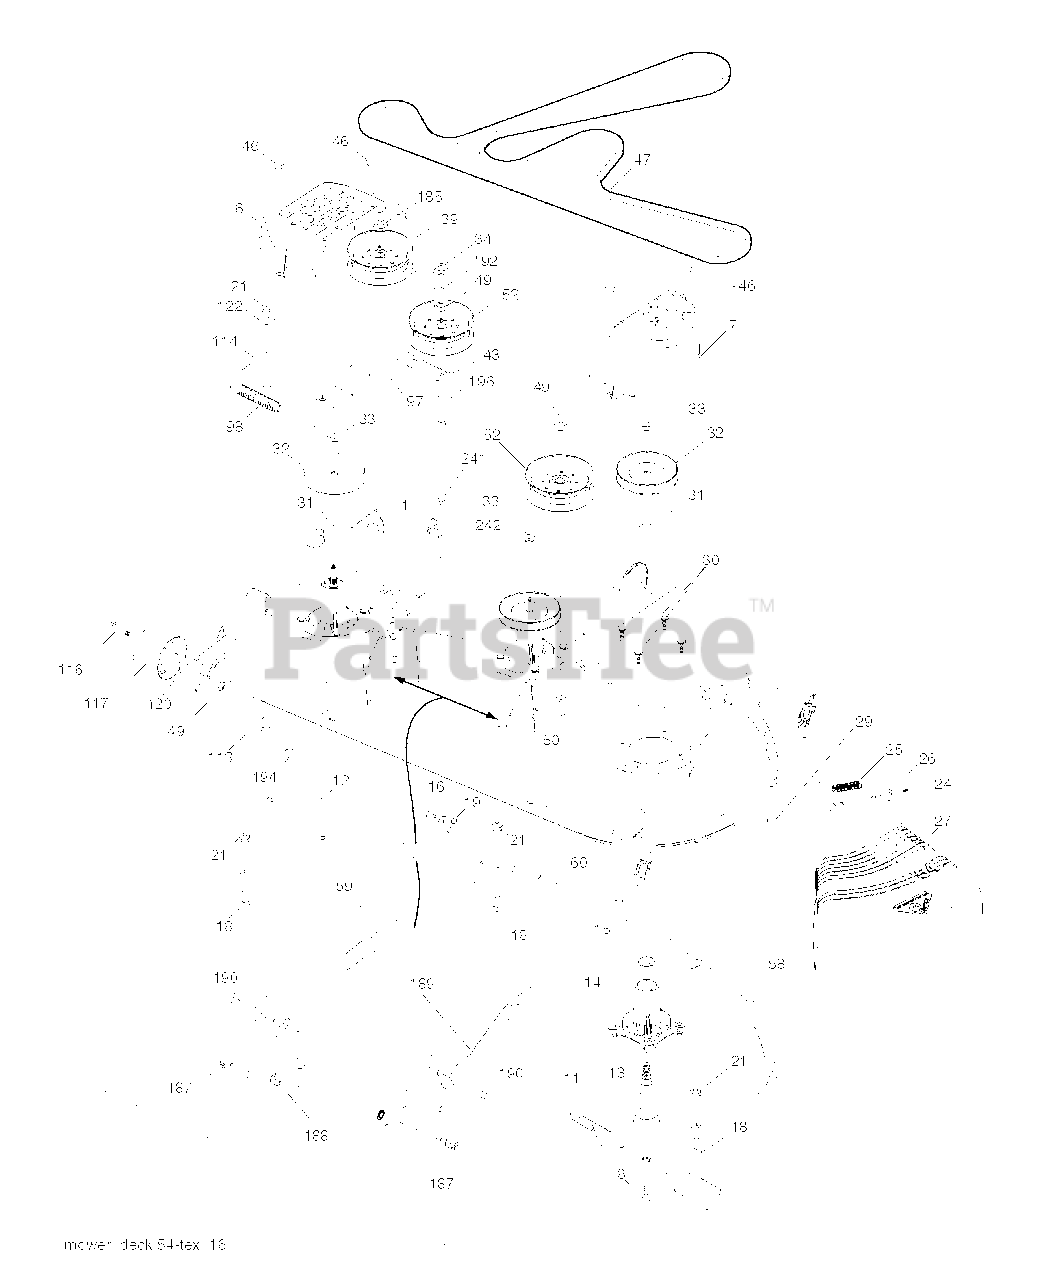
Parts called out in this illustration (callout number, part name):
1	DECK, COMPLETE, 54"E.HDHP.GWB.668
1	DECK, SHELL W/TUBES, 54".ORANGE
6	COVER.MANDREL.LH.54"20
7	COVER.MANDREL.RH.54.20
8	BOLT.WASHER.ASM.7/16-2
11	BLADE.BAGGING.54"
12	ROD.ANTI.SWAY.48/54"K4
13	SHAFT ASM MANDREL
14	HOUSING.MANDREL.4PT.
15	BEARING
16	WASHER
18	BOLT
19	PIN.COTTER.5/16.BOW TI
21	LOCKNUT
24	CAP-SLEEVE LT
25	SPRING, TORSION
26	NUT PUSH M
27	DEFLECTOR
29	ROD.HINGE
30	SCREW, WASHER HEAD
31	WASHER.SPACER.MANDREL
32	PULLEY/MANDREL
33	NUT.FLANGE.LOCK.TOP
34	LOCKNUT
39	RB PULLEY.IDLER.4.50/HUB SPEC
43	ARM.IDLER
46	SCREW.1/4-20X5/8
47	BELT.DRIVE.54."2006
49	NUT LOCK FLG 3/8-16 UNC
50	BOLT
52	PULLEY.IDLER.2006
58	BAFFLE.RIGHT.54"
59	BAFFLE.LEFT.54"
60	BAFFLE CENTER 54" MOWER
97	WASHER
98	SPRING, DECK DRIVE
113	BOLT CRT
114	ROD TENSION RELIEF
116	BOLT.SHOULDER.3/8-16X3-5/8.
117	WHEEL. GUAGE RALLY
120	WASHER
122	BUSHING.RELIEF.TENSION
185	NUT.LOCK.FLANGE.7/16
187	STUD.FASTNER.W/ANTI-ROTATE
188	NUT LOCK HEX FLANGE 5/16-18
189	ARM.SUSPENSION.MOWER
190	BOLT.SHOULDER
192	KEEPER.BELT.IDLER.54"T
194	BOLT.HEX.WASHER.HEAD.7/16-24X
196	BOLT
241	SCREW.TT.#10-32X.5.3/8.FLANGE
242	PORT.WASHOUT
242	COUPLING.QUICK CONNECT
